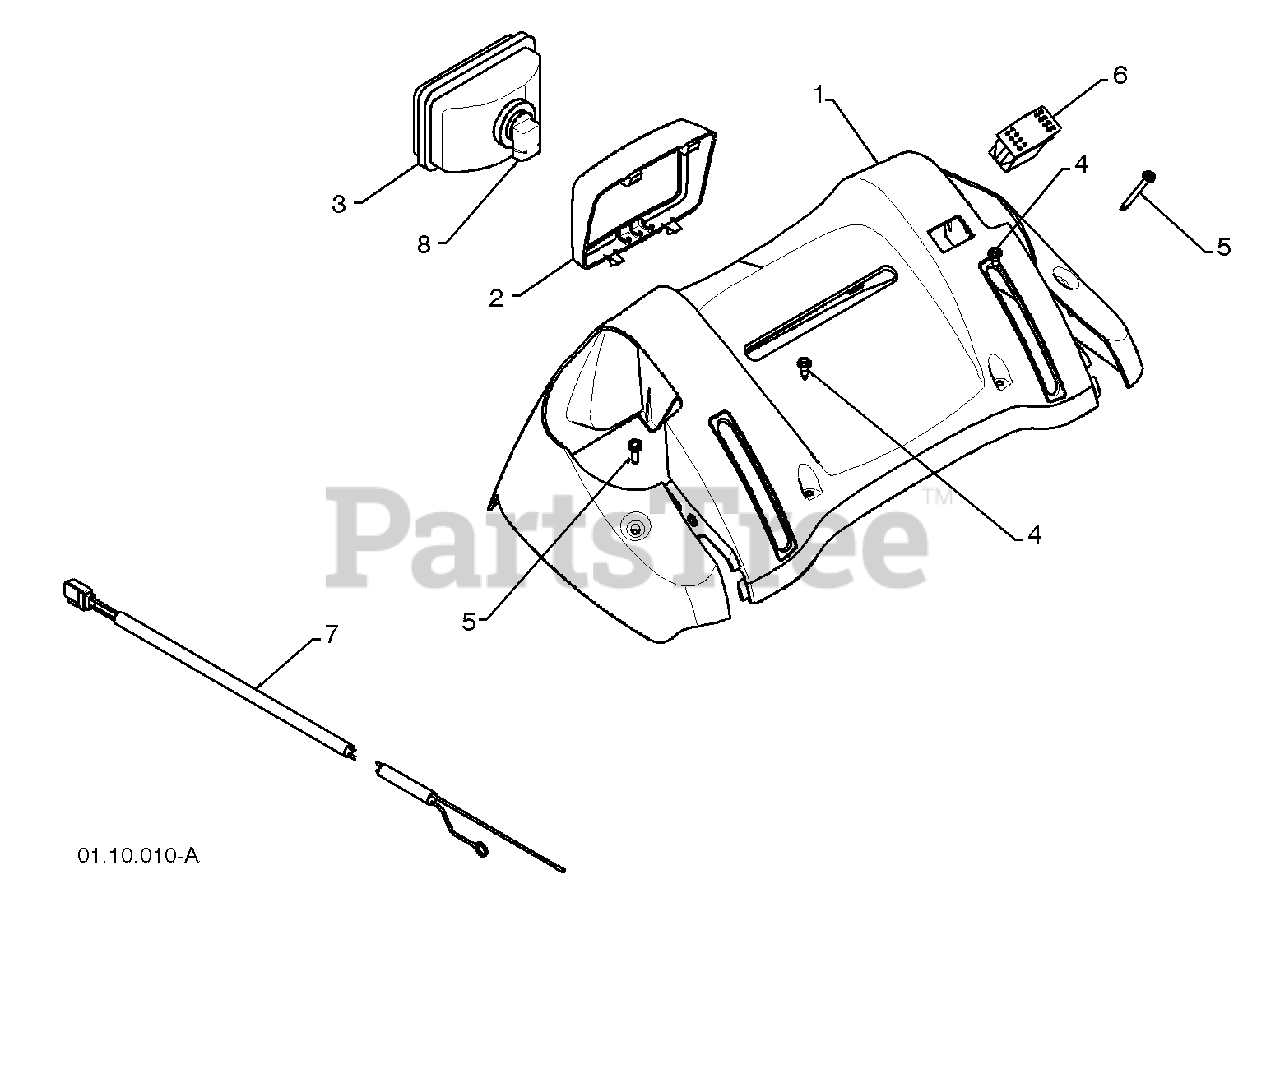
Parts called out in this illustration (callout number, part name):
1	CONSOLE PANEL GRAY
2	HEADLIGHT BEZEL GRAY
3	HALOGEN HEADLIGHT
4	SHOULDER SCREW 10-24 X .625
5	SCREW 10-24 X 1.25
6	GRIP SWITCH
7	WIRE HARNESS
